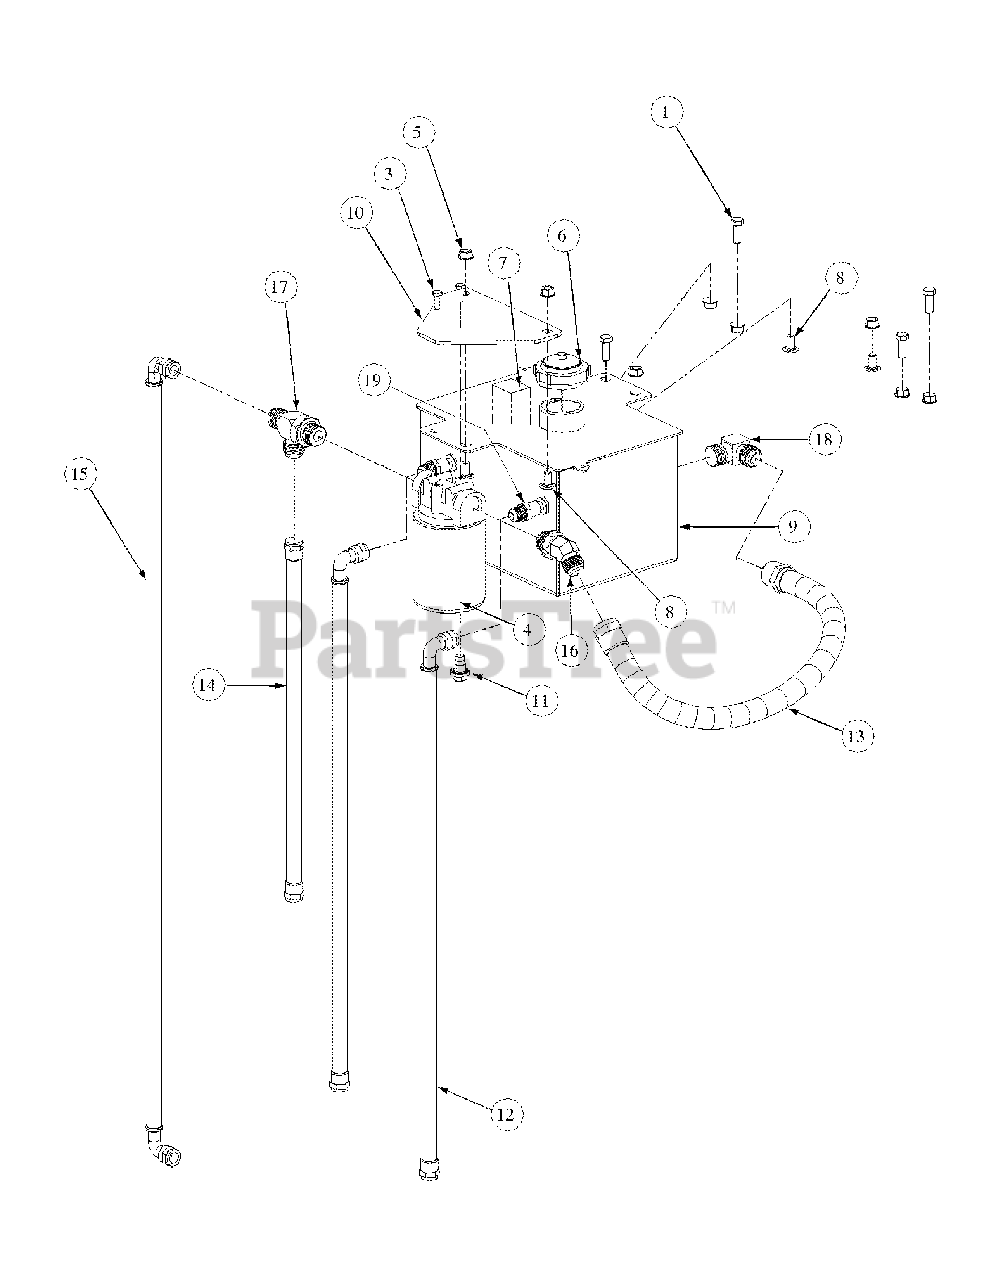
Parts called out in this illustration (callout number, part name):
1	Hex Cap Screw, 3/8-16, 1
2	Protective Hose Cover
3	Hex Cap Screw, 1/4-20, .75
4	Filter Head 3/4
5	Hex Nut Flange Lock, 3/8-16
6	Cap, Hydro Oil Tank
7	Decal Oil Only 20W50
8	Carriage Bolt, 3/8-16 x .75 LG.
9	Hydraulic Tank Assembly
10	Mounting Plate Oil Filter
11	Oil Pan Drain w/ Seal and Plug
12	Gearbox to Tank Hose Assembly
13	Tank to Filter Hose Assembly
14	Filter to Left Hand Pump Hose Assembly
15	Filter to Right Hand Pump Hose Assembly
16	Fitting, 45 degree
17	Fitting Tee, 3/4 x 1/2 x 1/2
18	Fitting Elbow, 1/2 x 1/2
19	Fitting, 3/8 NPT, 1/2 Flare
